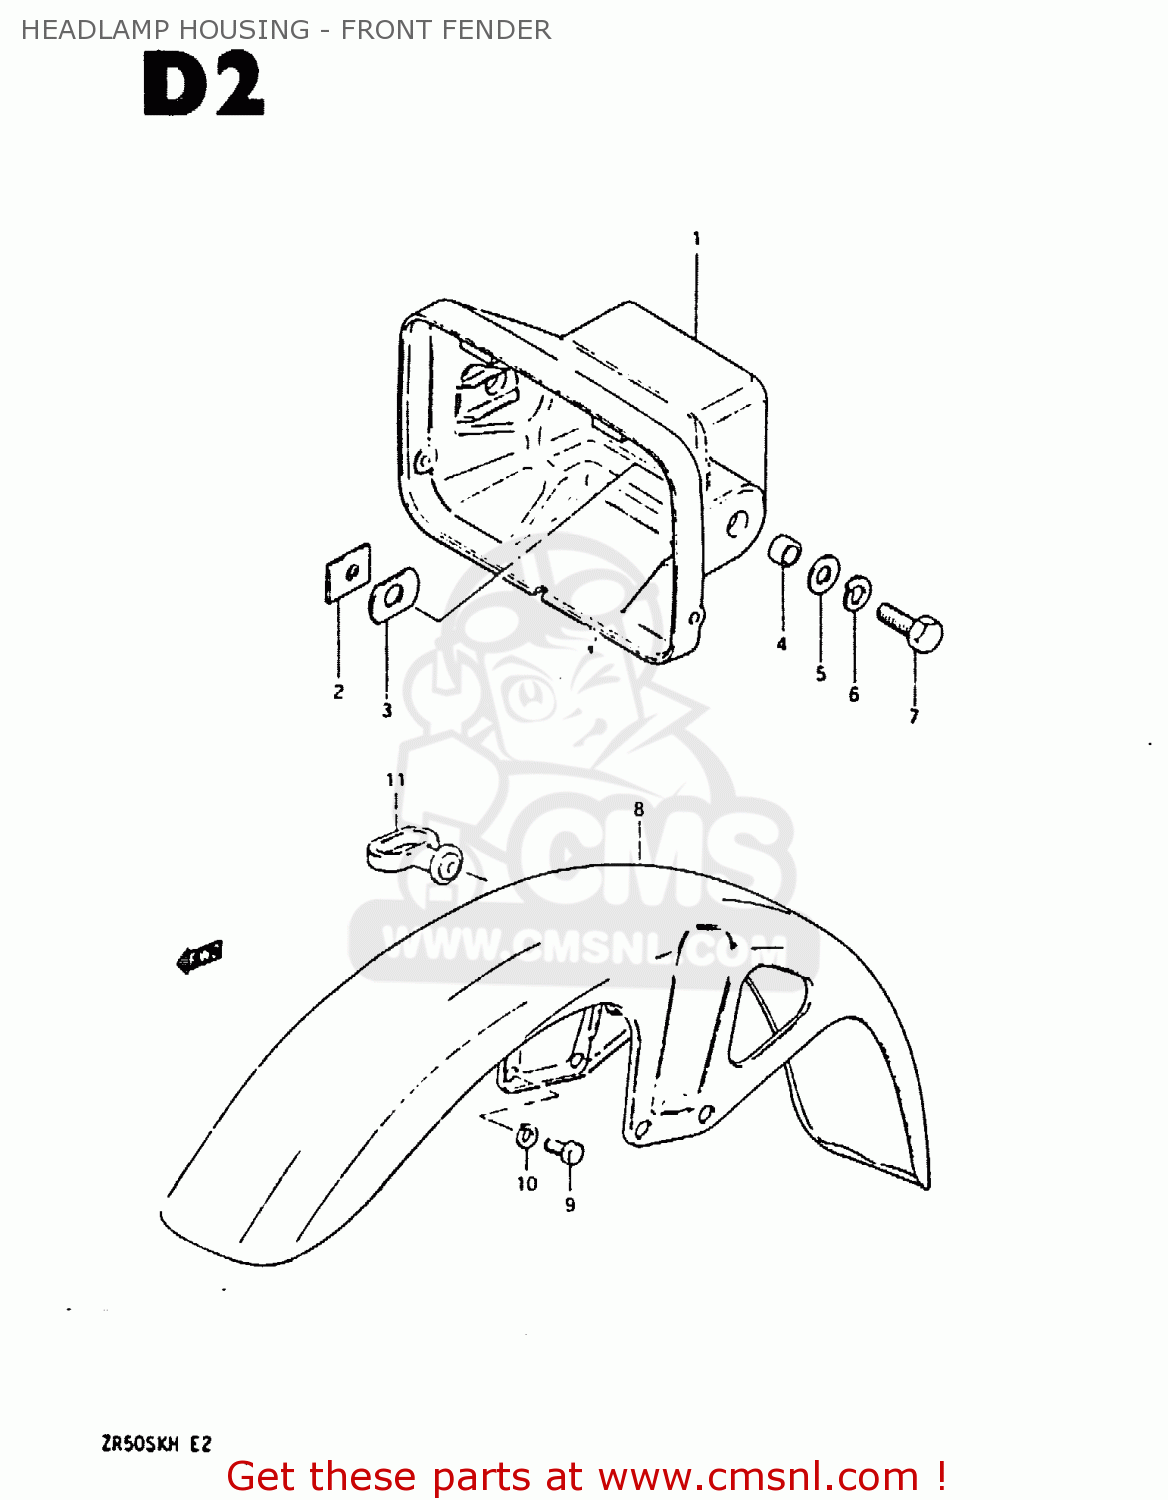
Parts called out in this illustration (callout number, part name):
1	HOUSING, HEADLAMP (BLACK)
2	PLATE,HEADLAMP HOUSING
3	CUSHION
4	SPACER (8.8X12X7)
5	WASHER
6	LOCK WASHER
7	BOLT
8	FENDER, FRONT
9	BOLT,8X16
10	LOCK WASHER
11	GUIDE,CABLE
